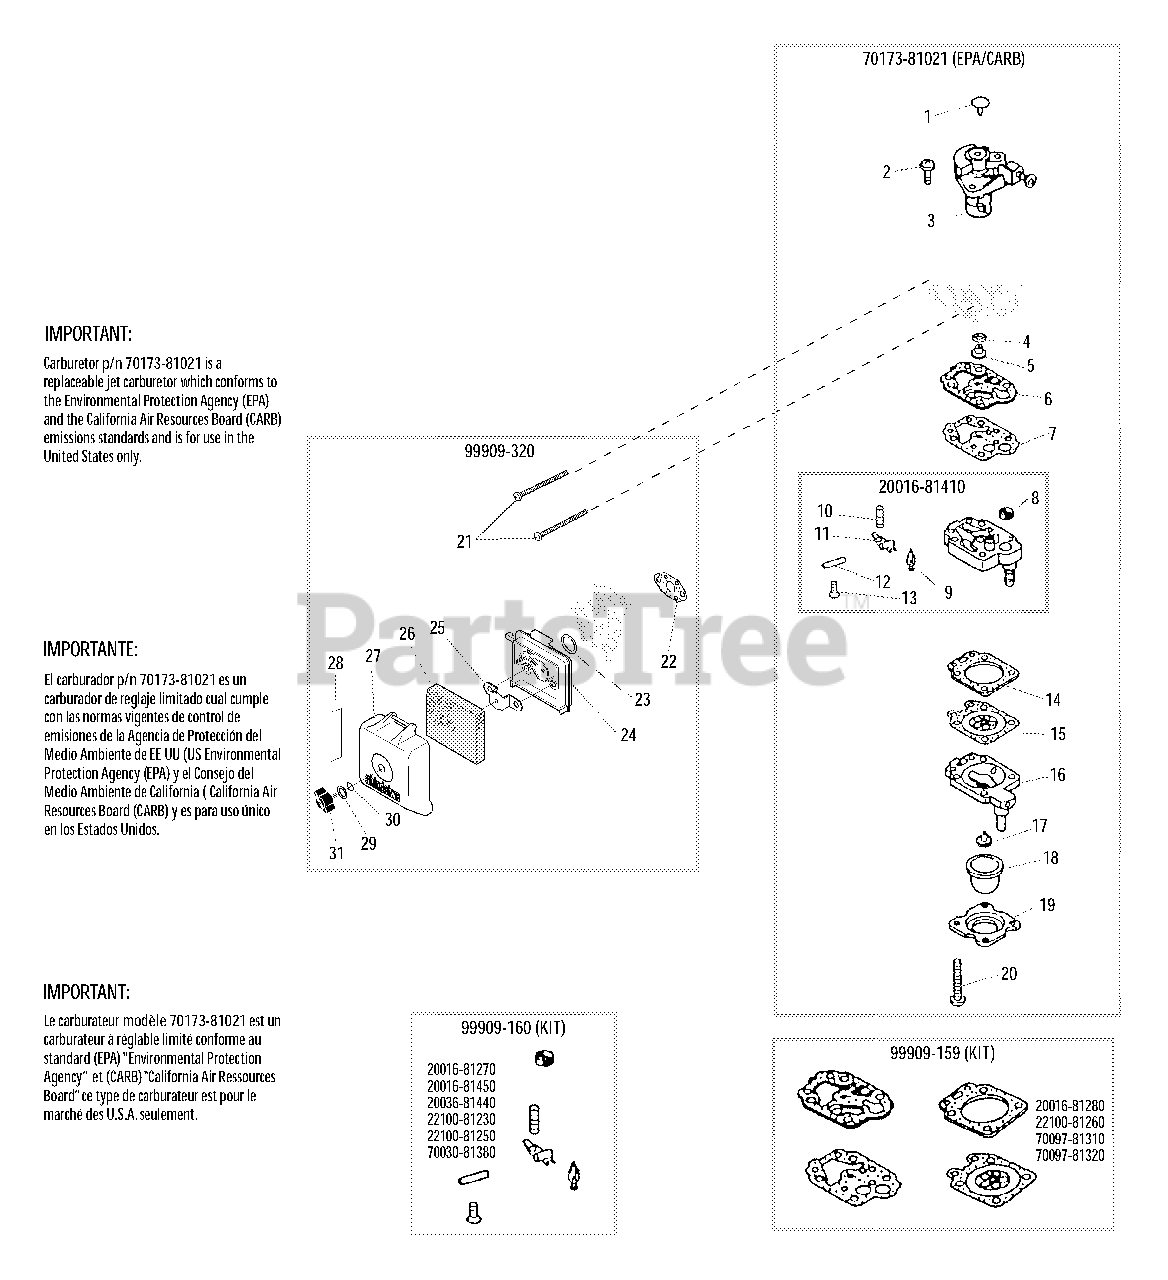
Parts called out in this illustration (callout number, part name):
1	PLUG, WELCH
2	SCREW
3	THROTTLE VALVE ASSY
4	O-RING
5	JET, MAIN - 38
6	GASKET, PUMP
7	DIAPHRAGM, PUMP
8	STRAINER
9	VALVE, INLET NEEDLE
10	SPRING, METERING LEVER
11	LEVER, METERING
12	PIN, METERING LEVER
13	SCREW, METERING LEVER PIN
14	GASKET, METERING
15	DIAPHRAGM, METERING
16	BASE, PURGE
17	VALVE, CHECK
18	BULB, PURGE
19	RETAINER, PURGE BULB
20	SCREW, PUMP COVER
21	SCREW - 5X67
22	GASKET
23	O-RING - 15
24	CASE, AIR FILTER
25	PLATE, PREVENT
26	FILTER, AIR - FOAM
27	COVER, AIR FILTER
28	LABEL - CHOKE
29	WASHER - CONICAL
30	O-RING
31	THUMBSCREW
20016-81410	PUMP BODY ASSY
70173-81021	CARBURETOR
99909-159	DIAPHRAGM/GASKET KIT
99909-160	REPAIR KIT
99909-320	AIR FILTER ASSY
